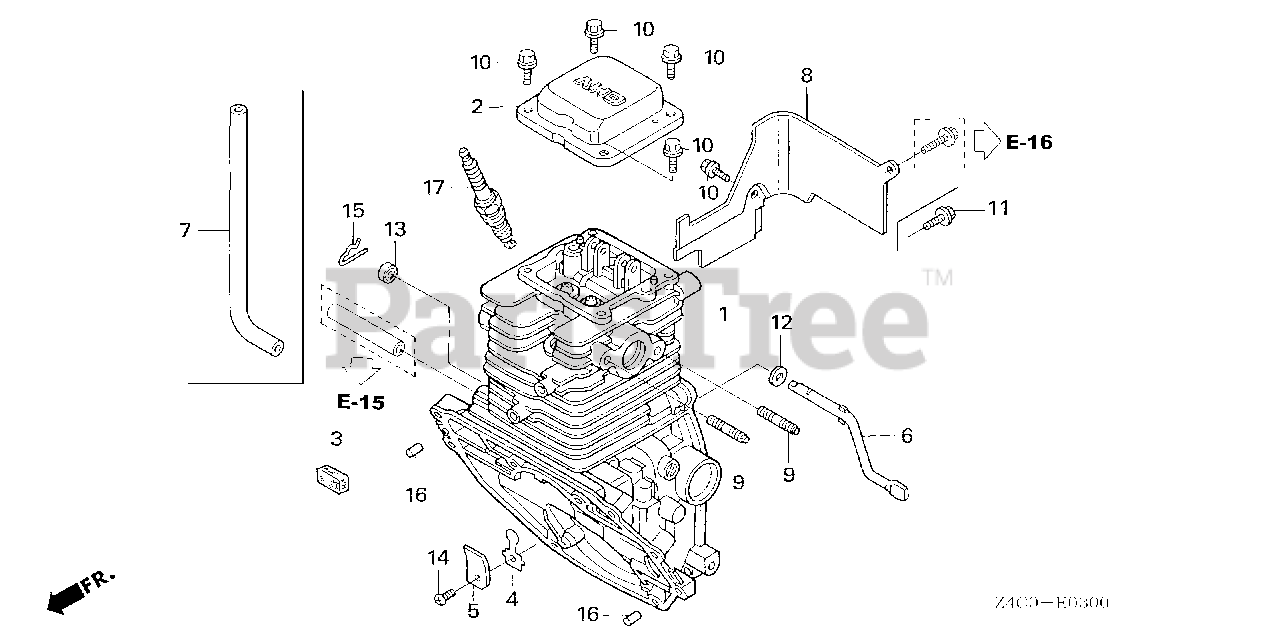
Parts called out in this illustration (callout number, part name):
2	COVER, HEAD
3	FILTER, BREATHER
4	VALVE, OIL OUTLET
5	PLATE, STOPPER
6	SHAFT, GOVERNOR ARM
10	BOLT, FLANGE (5X12)
12	WASHER (5.2X9)
13	OIL SEAL (5X11X5)
14	SCREW, PAN (3X5)
15	PIN, LOCK (6MM)
16	ROLLER (6X15)
17	SPARK PLUG (U14FSR-UB) (DENSO)
17	SPARK PLUG (CR4HSB) (NGK)
17	SPARK PLUG (U16FSR-UB) (DENSO)
17	SPARK PLUG (CR5HSB)
